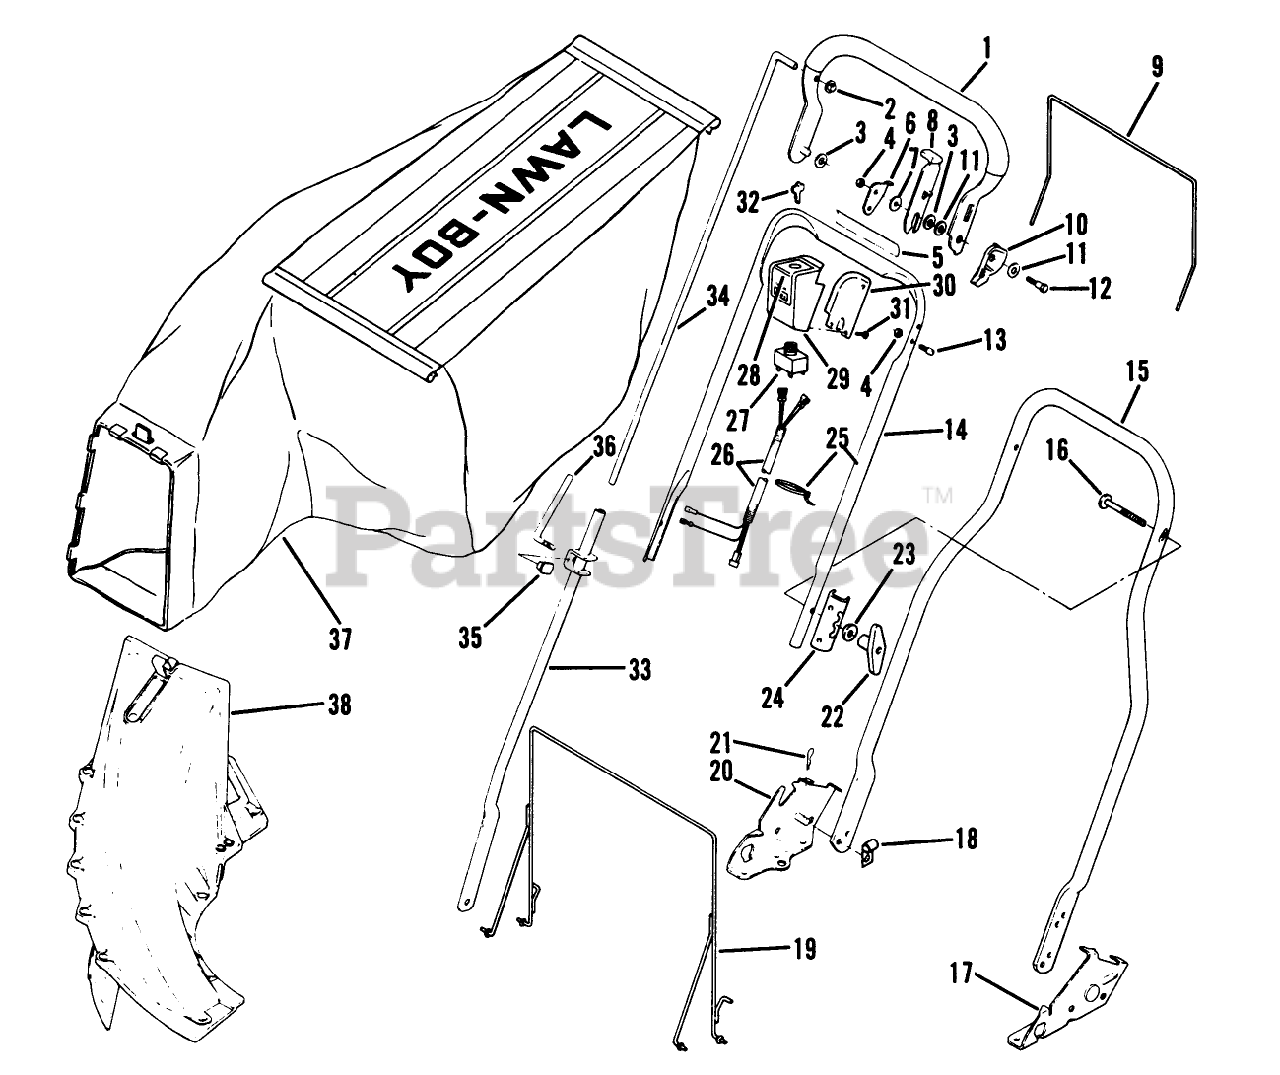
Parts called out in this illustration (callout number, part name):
3	WASHER M
4	LOCKNUT E
6	HANDLE STOP
7	WASHER
8	LEVER LOCKOUT
9	HANGER
12	BOLT PIONEER
13	SCREW-HANDLE STOP
14	HANDLE
20	HANDLE BRACKET
21	HAIR PIN
22	NUT-WING
23	WASHER-CURVED
24	BRACKET R/B 613462
29	HOUSING SWITCH
34	ROD CONTROL
